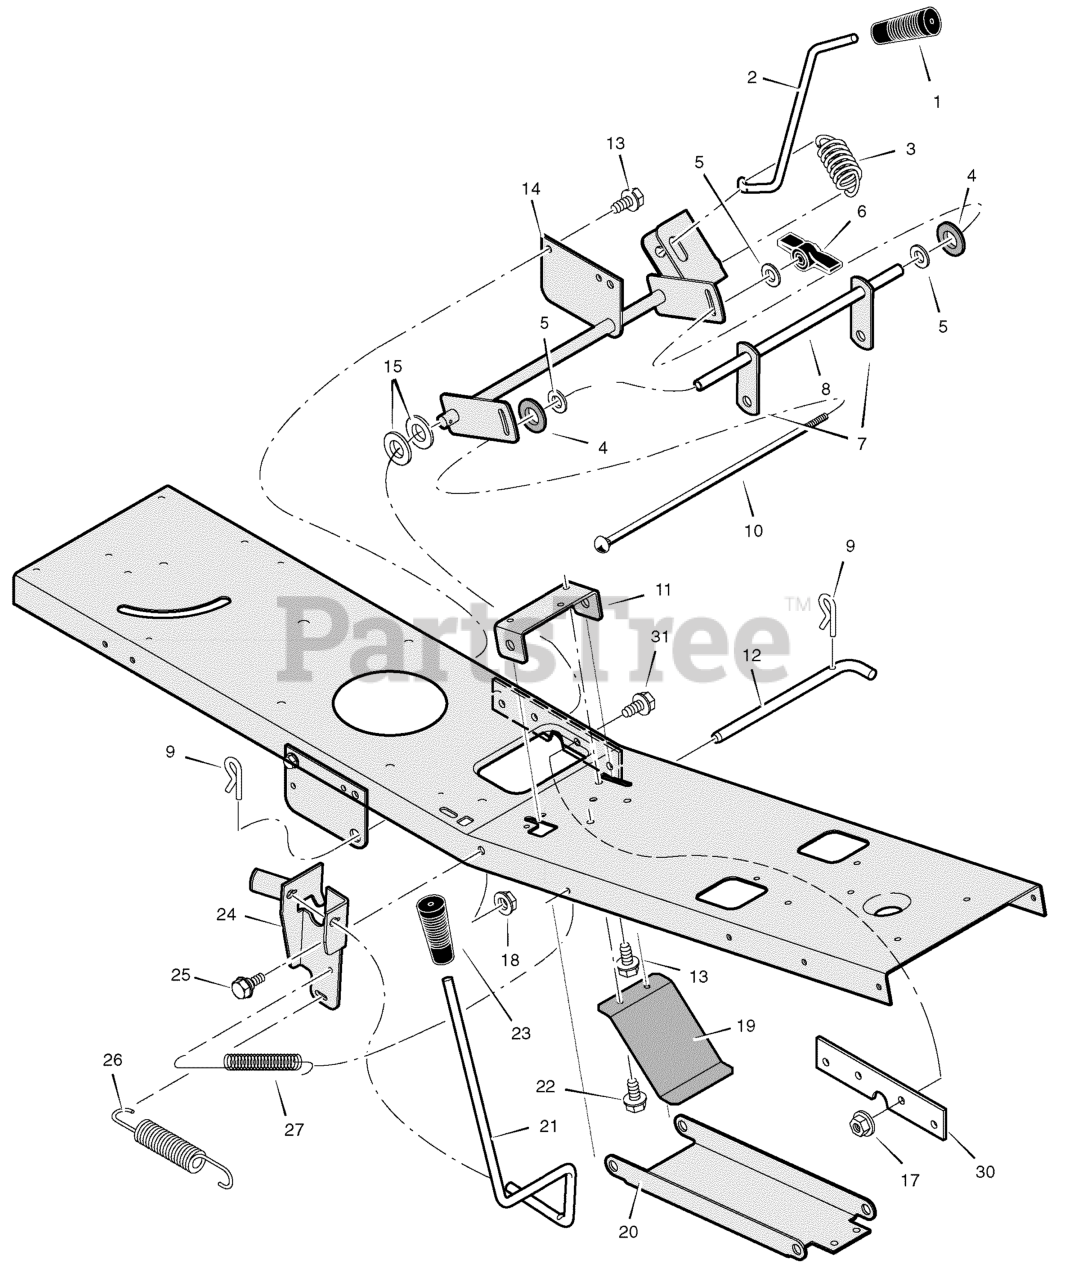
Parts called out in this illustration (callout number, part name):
1	GRIP, Lift Lever
2	Lever, Lift
3	Spring, Extension
4	Pad, Friction
5	Washer
6	Wingnut
7	Link, Lift
8	Tube, Spacer
9	Pin, Hair
10	Bolt, Carriage
11	Bracket, Front Hanger Pivot
12	Pin, Front Hanger
13	Screw
14	Arm Assembly, Lifter
15	Washer
17	Nut, Flange
18	Nut, Flange
19	Spring, Leaf
20	Hanger, Front
21	Lever, PTO
22	Screw
23	Grip, PTO
24	Bracket, PTO
25	Bolt, Shoulder
26	Spring, Extension
27	Spring, Extension
30	Plate, Reinforcement
31	Screw
